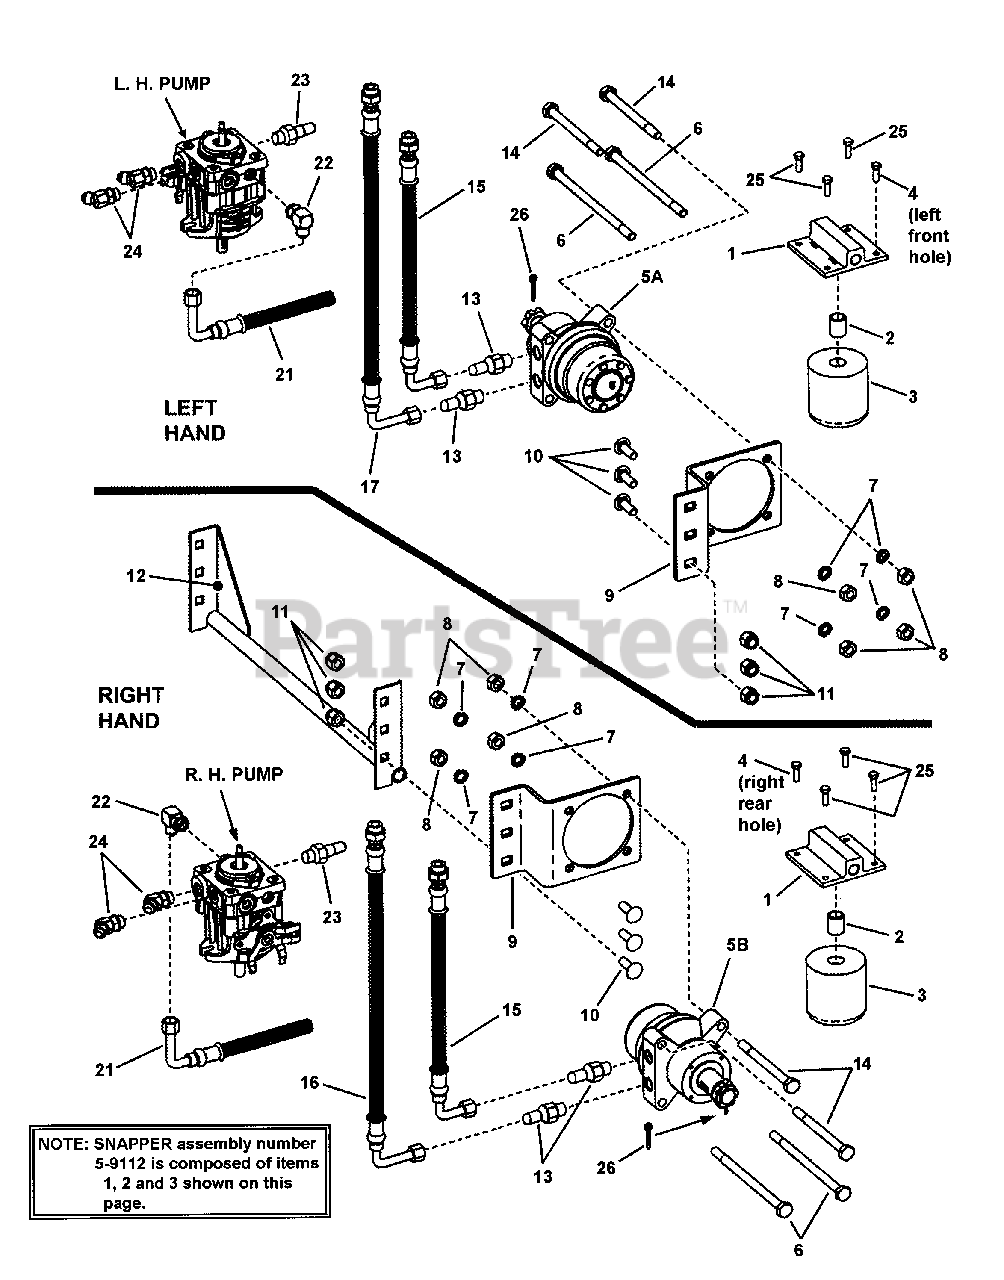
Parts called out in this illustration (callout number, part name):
1	MOUNT, Oil Filter
2	FITTING, Straight 1-12 UNF Thread
3	FILTER, Oil
4	SCREW, 3/8-16 x 3/4" Hex Washer Self-Tap
5A	MOTOR, Hydraulic, Left Hand
5B	MOTOR, Hydraulic, Right Hand
6	BOLT, 1/2-13 x 6" Hex Head Cap GR5
7	WASHER, 1/2" Split Lock
8	NUT, 1/2-13 HEX
9	PLATE, Mounting
10	BOLT, 1/2-13 x 1-1/2" Square Neck Carriage GR5
11	NUT, 1/2-13 Hex Nyloc
12	WELDMENT, Rear Crossbrace
13	CONNECTOR, Straight Hydraulic (Parker # 8-10 F5OLO-S)
14	BOLT, 1/2-13 x 3-3/4" Hex Head Cap
15	HOSE, 15-1/2" Hydraulic (Parker # F436JCJ9080808-15.50)
16	HOSE, 19-1/2" (Parker # F436BKJCJ5080808-19.5)
17	HOSE, 17-1/2" Hydraulic (Parker # F436BKJCJ5080808-17.5)
21	HOSE, 6-1/2" (Parker # R836BKJ9NR080008-6.5
22	CONNECTOR, 90 Degree Hydraulic (Parker # 8-6 C5OLO-S
23	CONNECTOR, Straight Hydraulic (Parker # 8-6 F5OLO-S)
24	CONNECTOR, 45 Degree Hydraulic (Parker # V5OLO-S)
25	SCREW, 5/16-18 x 3/4" Hex Washer Self-Tap
26	PIN, 9/64 x 1-1/2" Cotter
